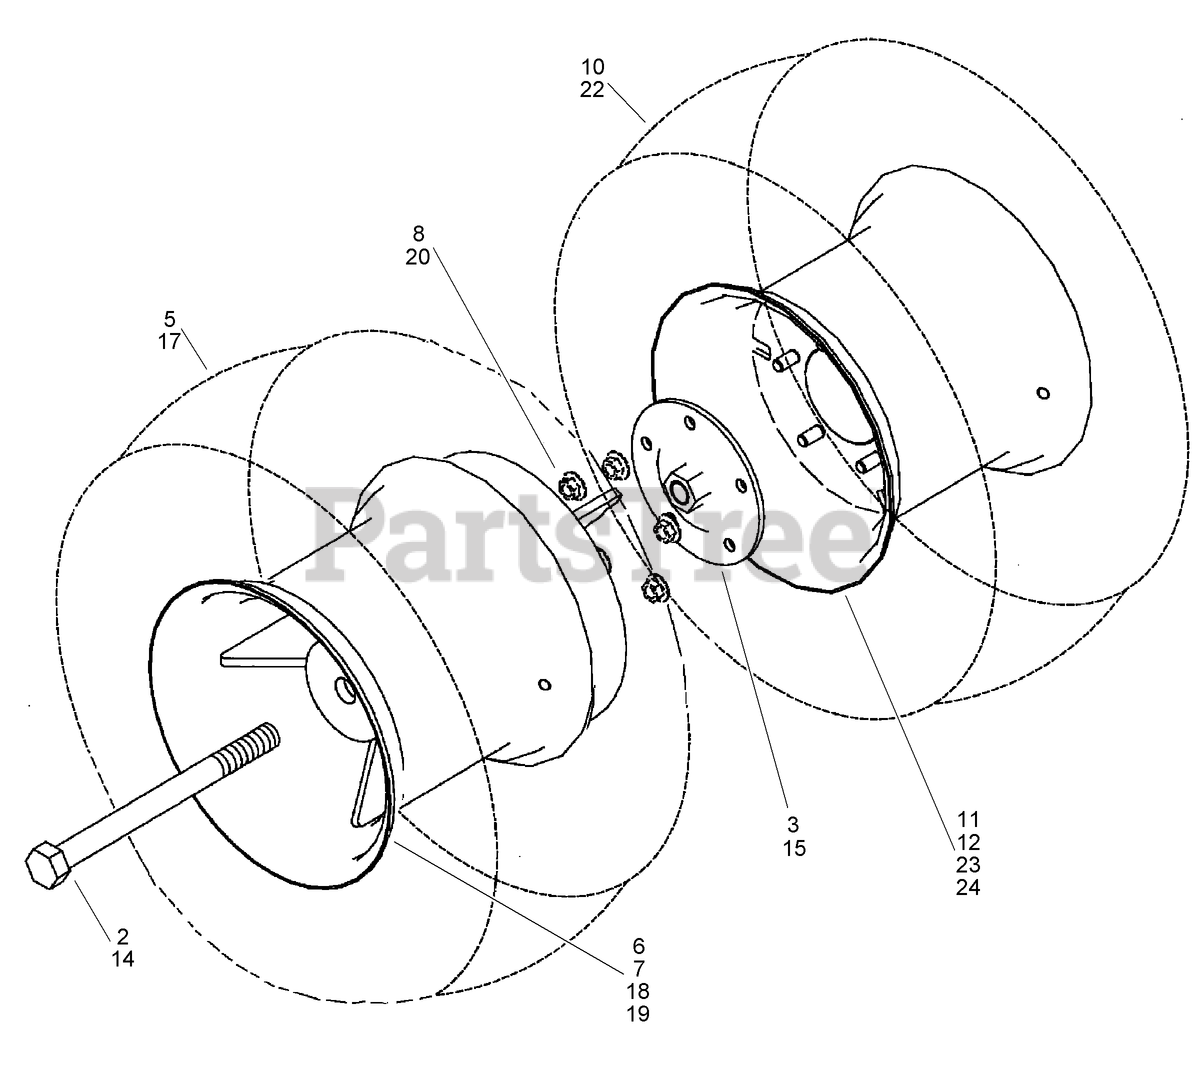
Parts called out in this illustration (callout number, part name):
2	SCREW-HH
3	PLATE-RETAINER
5	TIRE - 23 x 10.50 x 12 Galaxy (purchase locally)
6	WHEEL-DUAL
7	STEM - Valve, Tire Inflation
10	TIRE - 23 x 10.50 x 12 Galaxy (purchase locally)
11	WHEEL - Rim, 8.50 x 12 inch, Used with 10.50 x 12 Tire
12	STEM-Valve
14	SCREW-HH
15	PLATE-RETAINER
17	TIRE - 26 x 12 x 12 Galaxy (purchase locally)
18	WHEEL-DUAL
19	STEM - Valve, Tire Inflation
22	TIRE - 26 x 12 x 12 Galaxy (purchase locally)
23	WHEEL - Rim, Used with 26 x 12 x 12 Tire
24	STEM-Valve
